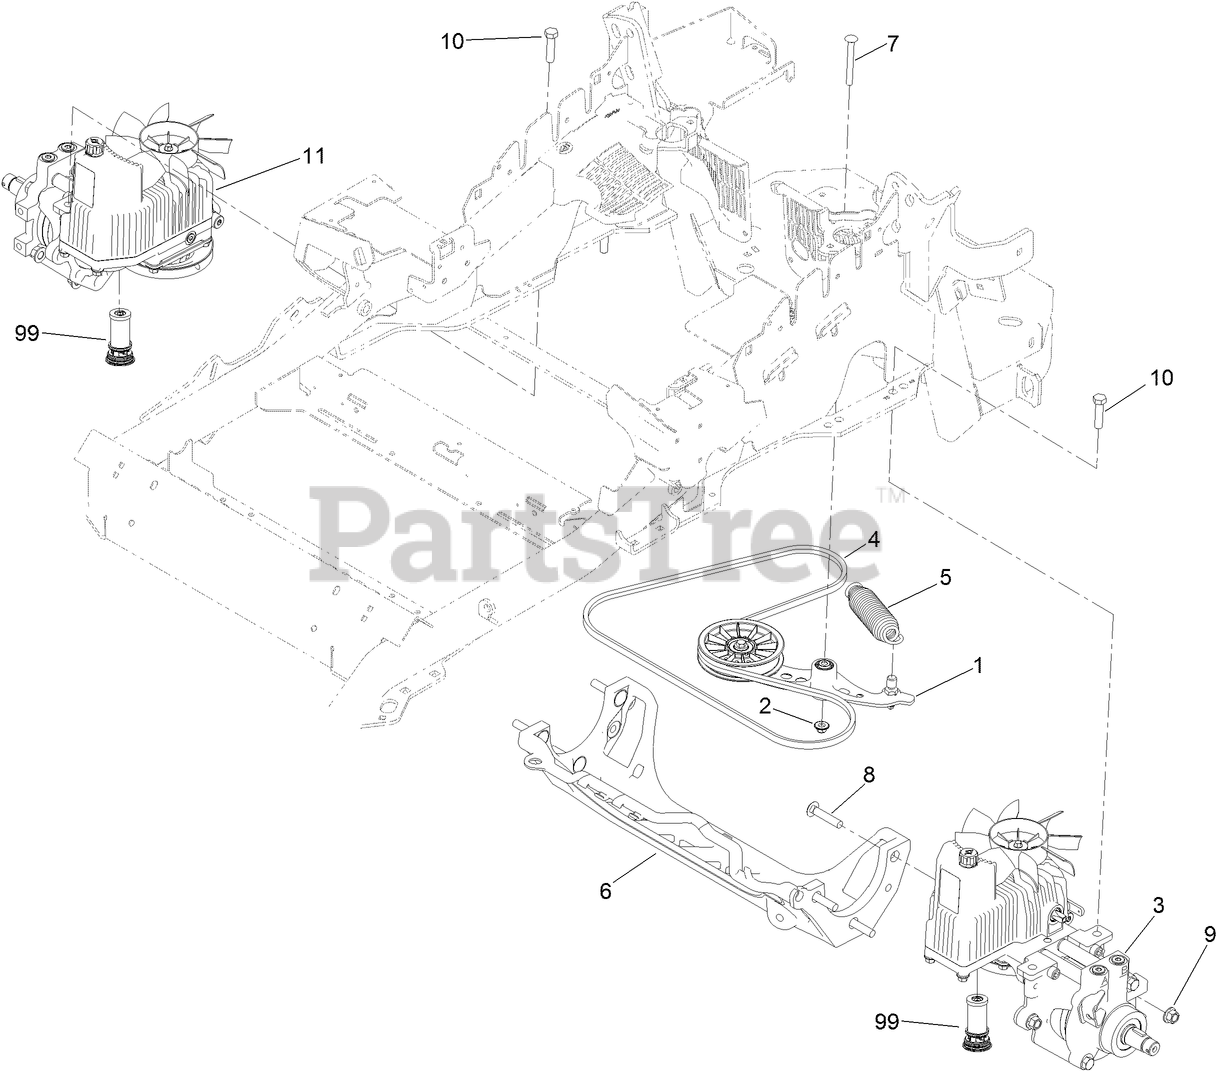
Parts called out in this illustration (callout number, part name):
1	PUMP IDLER ASM
2	NUT-FLANGE, NI
3	LH HYDRO ASM (12CC W/SHOCK)
4	BELT
5	EXTENSION-SPRING
6	CRADLE-HYDRO
7	BOLT-SHOULDER, CARRIAGE
8	SCREW-CARR
9	NUT-LOCK
10	SCREW-HH
11	RH HYDRO ASM (12CC W/SHOCK)
99	FILTER-HYDRO
